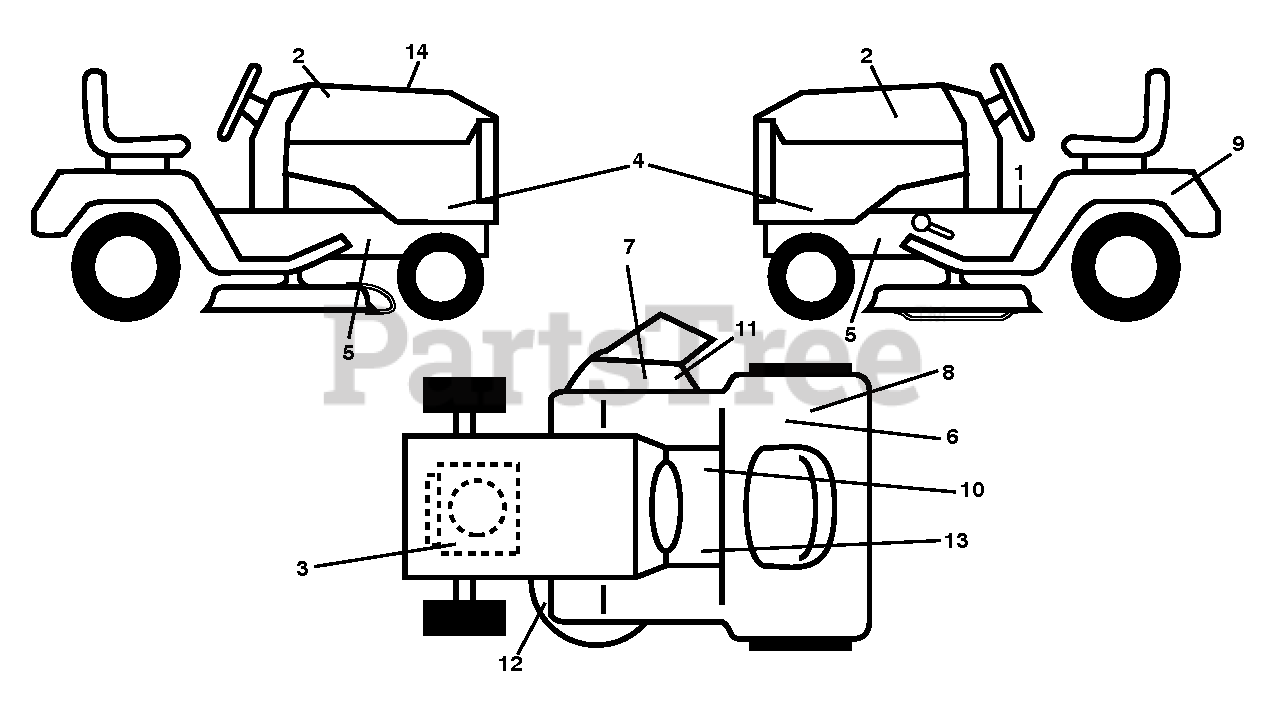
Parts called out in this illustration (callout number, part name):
1	LABEL
2	RP.DECAL.BADGE.170MM.TEXTLOGO
3	DECAL
6	DECAL 80 DBA
7	DECAL.INTERNATIONL.CUTFINGER
8	DECAL
9	DECAL BTRY SYMBOLS
10	DECAL PARK BRAKE
11	DECAL, DEFLECT WARNING
12	DECAL.V-BELT.SCHEMATIC.36/38/9
13	DECAL
